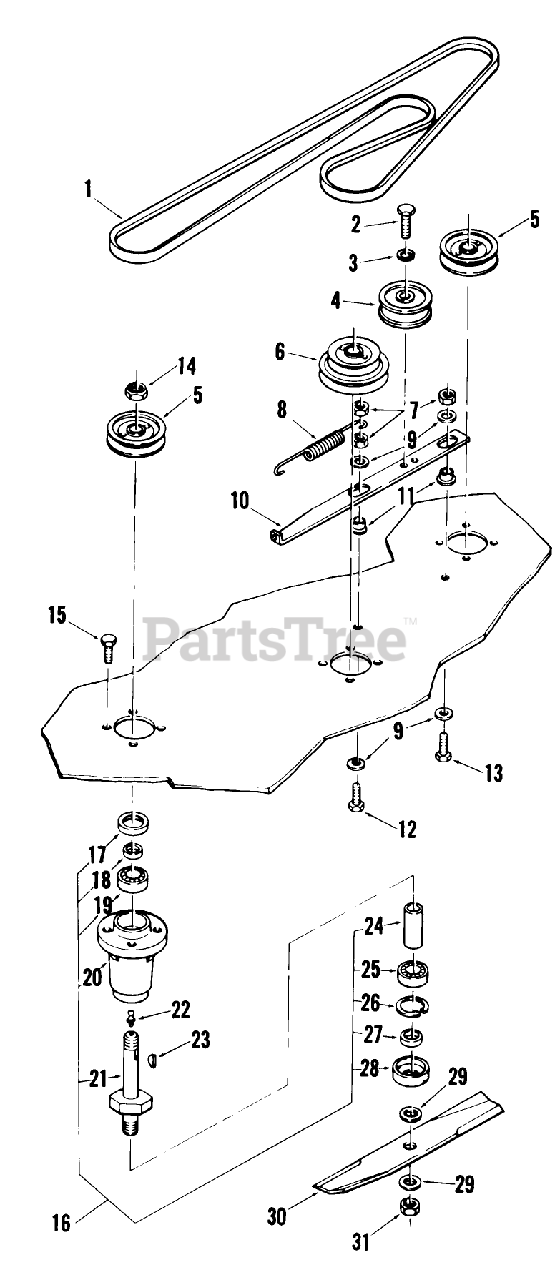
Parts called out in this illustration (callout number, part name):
1	V-BELT
5	PULLEY-BLADE DRIVE
6	PULLEY-48 MOWER SPDL
8	SPRING-EXTENSION
9	WASHER
10	BAR-IDLER SUPPORT
18	SPACER-SEAL
19	BEARING-BALL
23	Hi-Pro Key 3/16 x 5/8
24	SPACER
25	BEARING-BALL
26	Ring-Snap
27	SPACER-BLADE
30	BLADE KIT (3 PACK)
